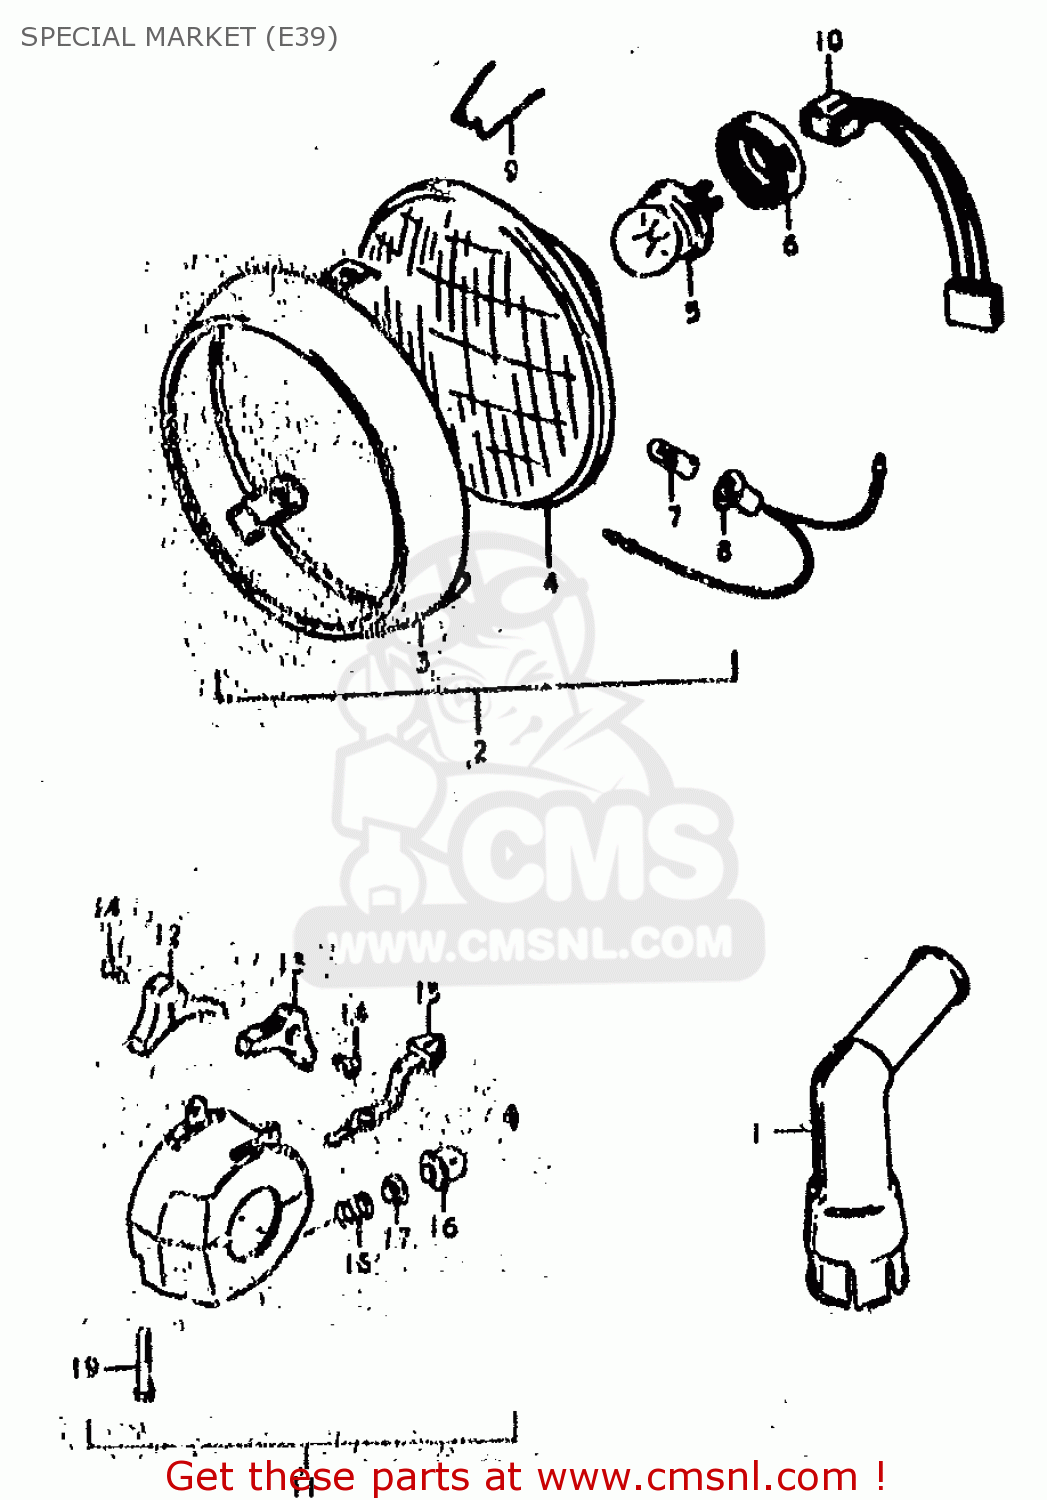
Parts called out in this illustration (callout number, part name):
1	CAP, SPARK PLUG (S)
2	HEADLAMP ASSY
3	RIM
4	UNIT
5	BULB(12V45/40W)
6	SETTER,BULB
7	BULB(12V4W)
8	SOCKET
9	SPRING,HEAD LA
10	LEAD WIRE,HEADLAMP
11	SWITCH ASSY,HANDLE LH
12	KNOB,LIGHTING SWITCH
13	KNOB,DIMMER SWITCH
14	SCREW
15	KNOB,TURNSIGNAL
16	BUTTON,HORN
17	CONTACT
18	SPRING
19	SCREW
